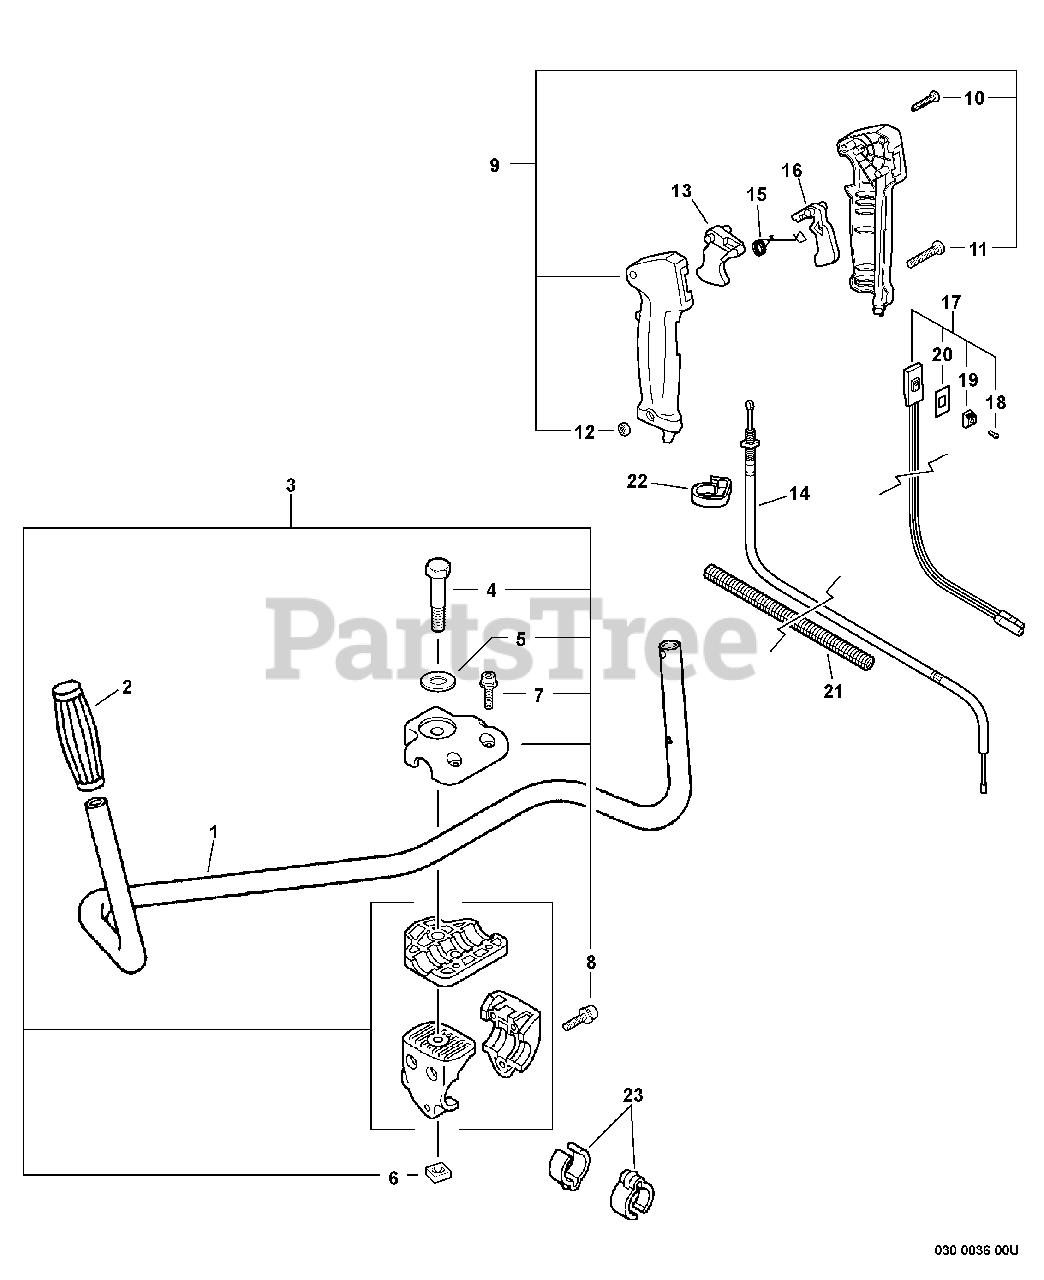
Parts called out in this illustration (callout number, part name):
1	HANDLE - FRONT
2	GRIP, HANDLE - LEFT
3	HANDLE BRACKET KIT
4	BOLT - 8X55
5	WASHER - 8
7	SCREW - 5X20
8	SCREW - 5X30
9	THROTTLE CONTROL ASSY
10	SCREW - 3X25
11	SCREW - 5X30
13	TRIGGER, THROTTLE
14	CABLE, THROTTLE
15	SPRING, LOCKOUT LEVER
16	LOCKOUT, THROTTLE
17	SWITCH, IGNITION
18	SCREW - 3X10
19	KNOB, SWITCH - ORANGE
20	COVER, SWITCH - STOP
21	TUBE, PROTECTIVE - CORRUGATED
